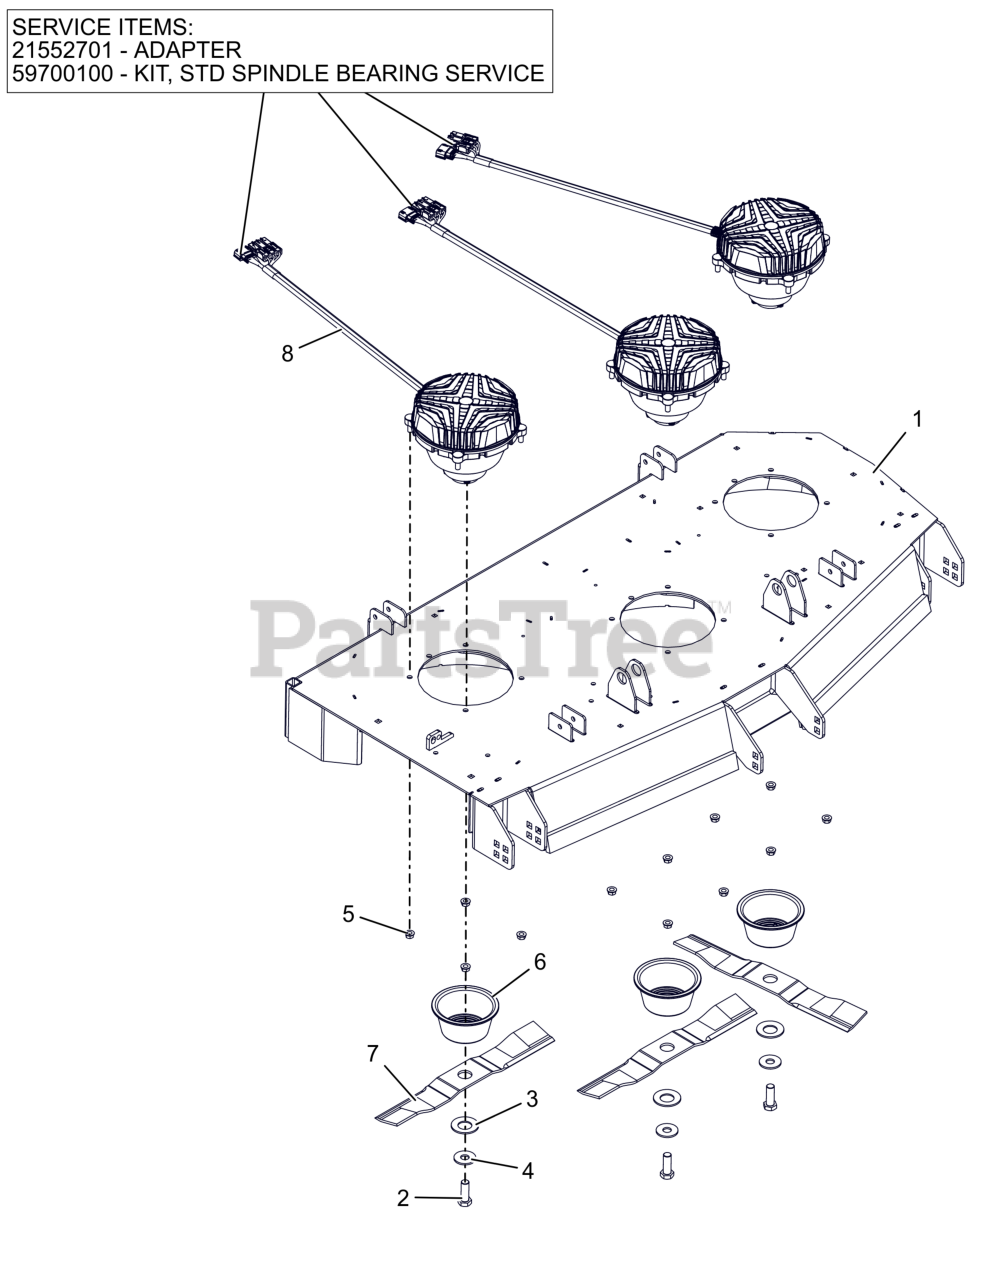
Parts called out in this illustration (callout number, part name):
1	WLDMT, 52" PSEV SIDE DISCH DECK (ORANGE)
2	BLT, HEX .62-18X1.75 G8 ZCC
3	WSHR, BLVL - .56X28.5X3 PHOS.COAT
4	WSHR, HRDN 0.687X1.75X0.134 HRD
5	NUT-LK-CTR-FLG .375-16 GF ZCC
6	GUARD, SPINDLE LOWER
7	BLADE- MOWER-18.00" LOW
8	MOTOR, DECK - 48"/52" CW
8	ADAPTER
8	KIT,STD SPINDLE BEARING SERVICE
